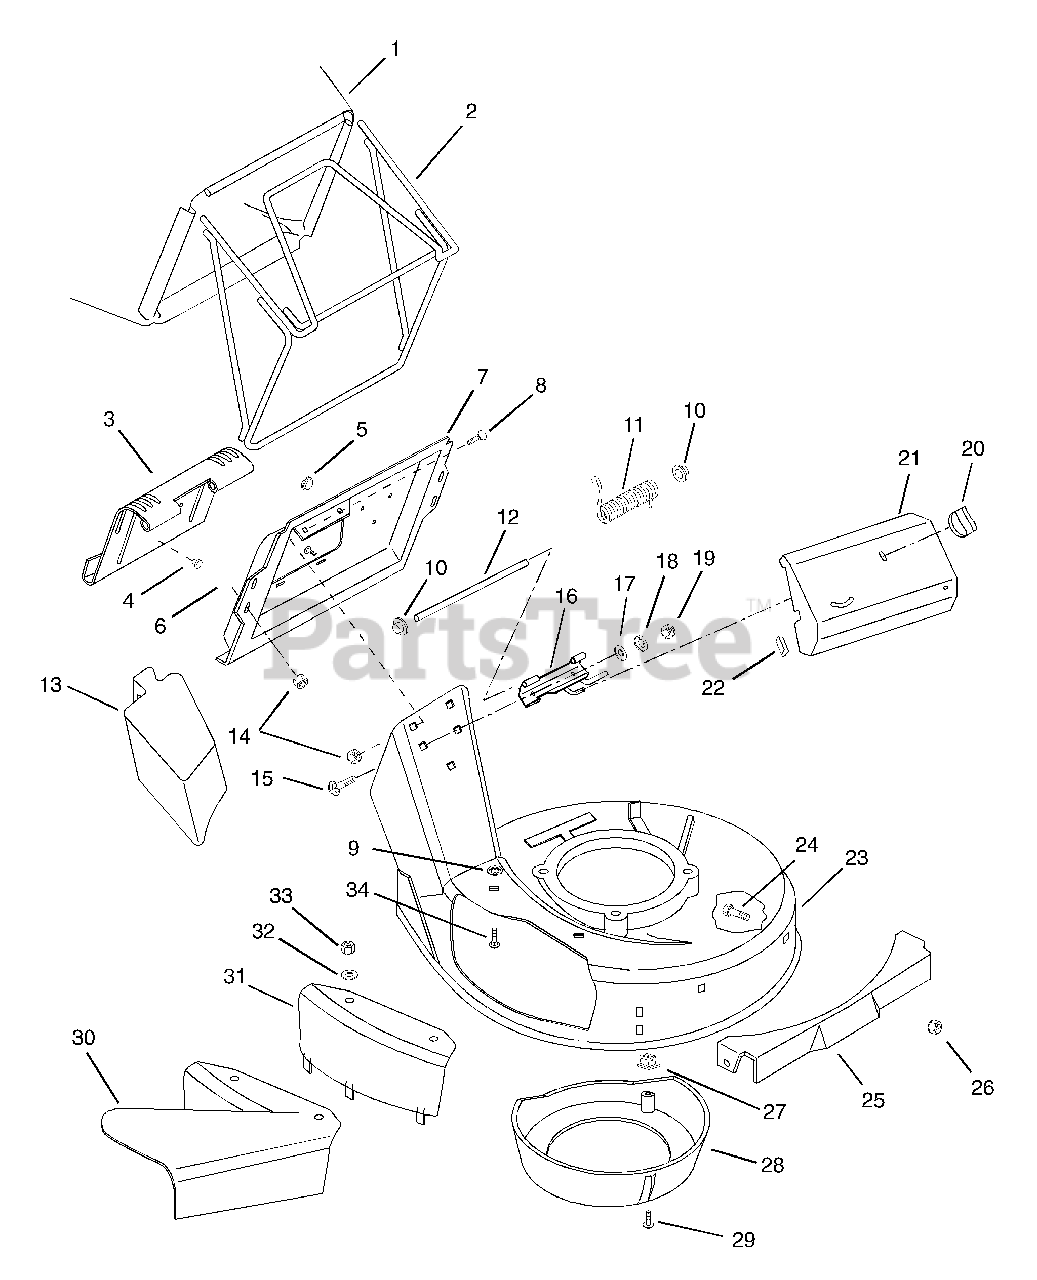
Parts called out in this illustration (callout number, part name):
1	Bag-Consumer Black
2	Bagger Frame
3	Catcher Plate Door
4	Button Bumper
6	Screw-Tapping 10-24 x .38 Hex Washer Head
7	Catcher Plate
8	Bolt-Round Head Square Neck .25-20 x .38
9	Nut-Push .312
10	Push Nut, .25
11	Spring-Torsion .120 x .68 x 3.09
12	Door Pin
13	Mulch Master Mulcher Accessory
14	Nut-Locking-Flange .25-20
15	Bolt-Round Head Square Neck .25-20 x .75 Grade 5
16	Hinge Base Weldment
17	Washer-Flat-Steel .312 x .734 x .065
18	Washer-Locking .25 x .077
19	Nut-Hex .25-20
20	Nut-Wing
21	Drive Cover
22	Trim Bumper
23	Mower Pan Head w/ Decals
24	Bolt, Round Head Square Neck .31-18 x .50
25	Front Panel
26	Nut-Locking-Center .31-18
27	Plastic Grommet
28	Center Baffle
29	Screw-Tapping 10-16 x .62 Hex Washer Head
30	Side Discharge Assembly
31	Side Discharge Cover
32	Washer-Flat-Steel .406 x .812 x .065
33	Nut-Locking-Center .31-18
34	Bolt-Round Head Square Neck .31-18 x .75
